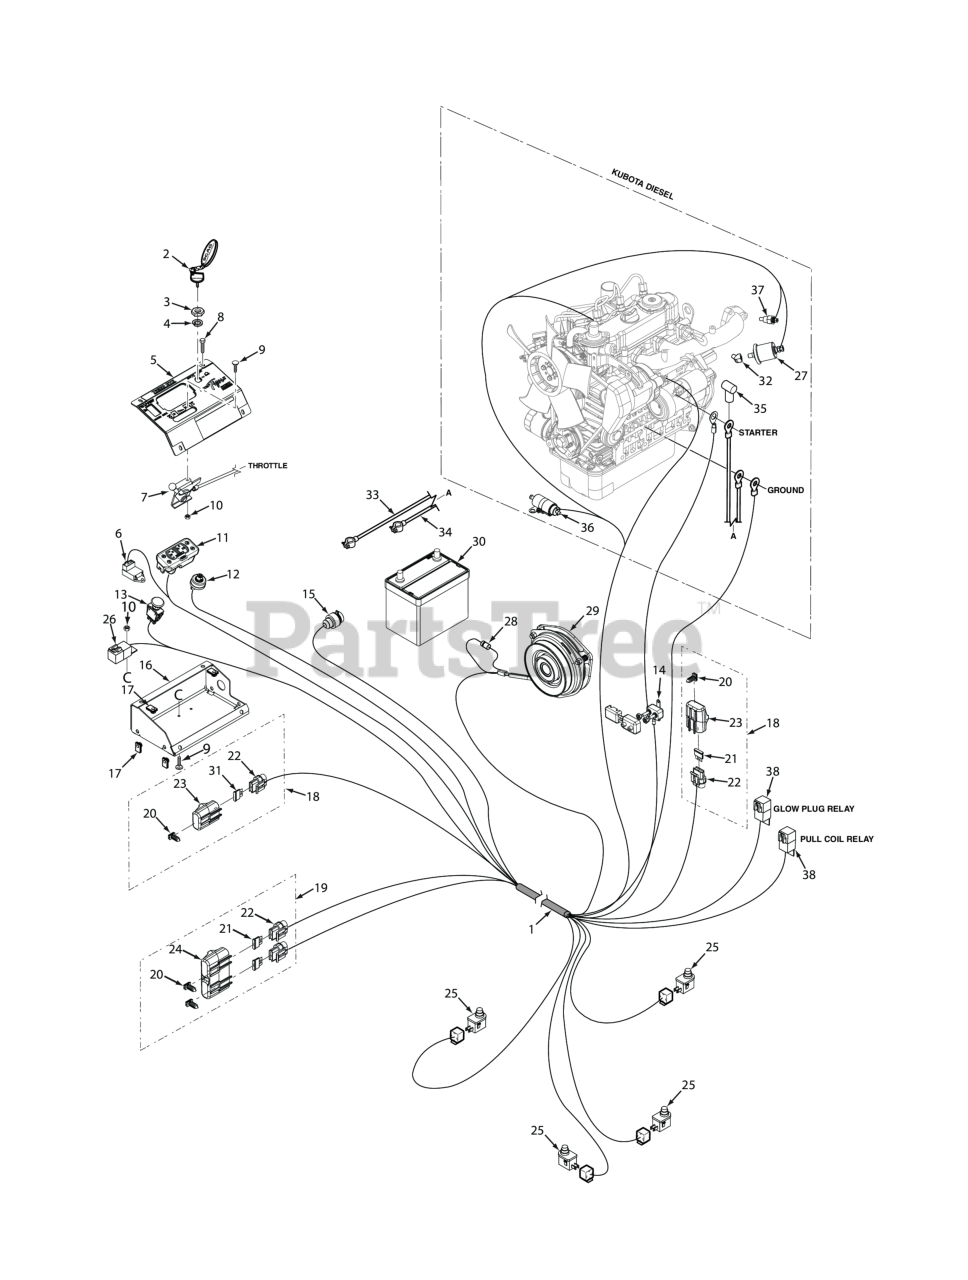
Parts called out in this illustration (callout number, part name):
2	Key, Assembly w/Fob
3	Nut, 5/8-32 Special
4	LOCK WASHER, 5/8" INTERNAL TOOTH
5	Instrument Panel w/Decal
6	Timer, Glow Plug
7	Cable, Control (Throttle)
8	Bolt, Hex Head Serrated Flange 1/4-20 x 3/4"
9	Bolt, Carriage #10-24 x 1/2"
10	Nut, Elastic Stop #10-24
11	Tiger Eye, Cluster Gauge
12	KEY SWITCH(INCLUDES MOUNTING HARDWARE)
13	Switch, PTO - 10 Amp
14	50 Amp Breaker
15	Power Plug, 12V
16	Base, Instrument Panel
17	Bolt, Hex Head 3/8-16 x 1"
18	Single Fuse Assy., Excluding Fuse
19	Double Fuse Assy.
20	Clip, Fuse Holder
21	FUSE, 20 AMP BLADE TYPE AUTOMOTIVE
22	Fuse Holder Assembly
23	Cover, Sealed Single
24	Cover, Sealed Double
25	Switch, Interlock, Normally Open
26	Relay, 12V 40 AMP Standard
27	Sender Unit, Oil Pressure
28	Diode, 600V 6 Amp
29	Clutch Assembly, GT3.5 (Diesel Engine)
30	Battery, 525 CCA
31	Fuse, 5 Amp
32	Elbow, 45 Degree Street
33	Battery Cable, 14" Red w/Braid
34	Battery Cable, 21" Black
35	Boot, Positive Battery Terminal
36	Solenoid, Fuel Shut-Off
37	Temperature Sensor, Engine Coolant
38	Relay, 12V 40 AMP Hi Capacity
